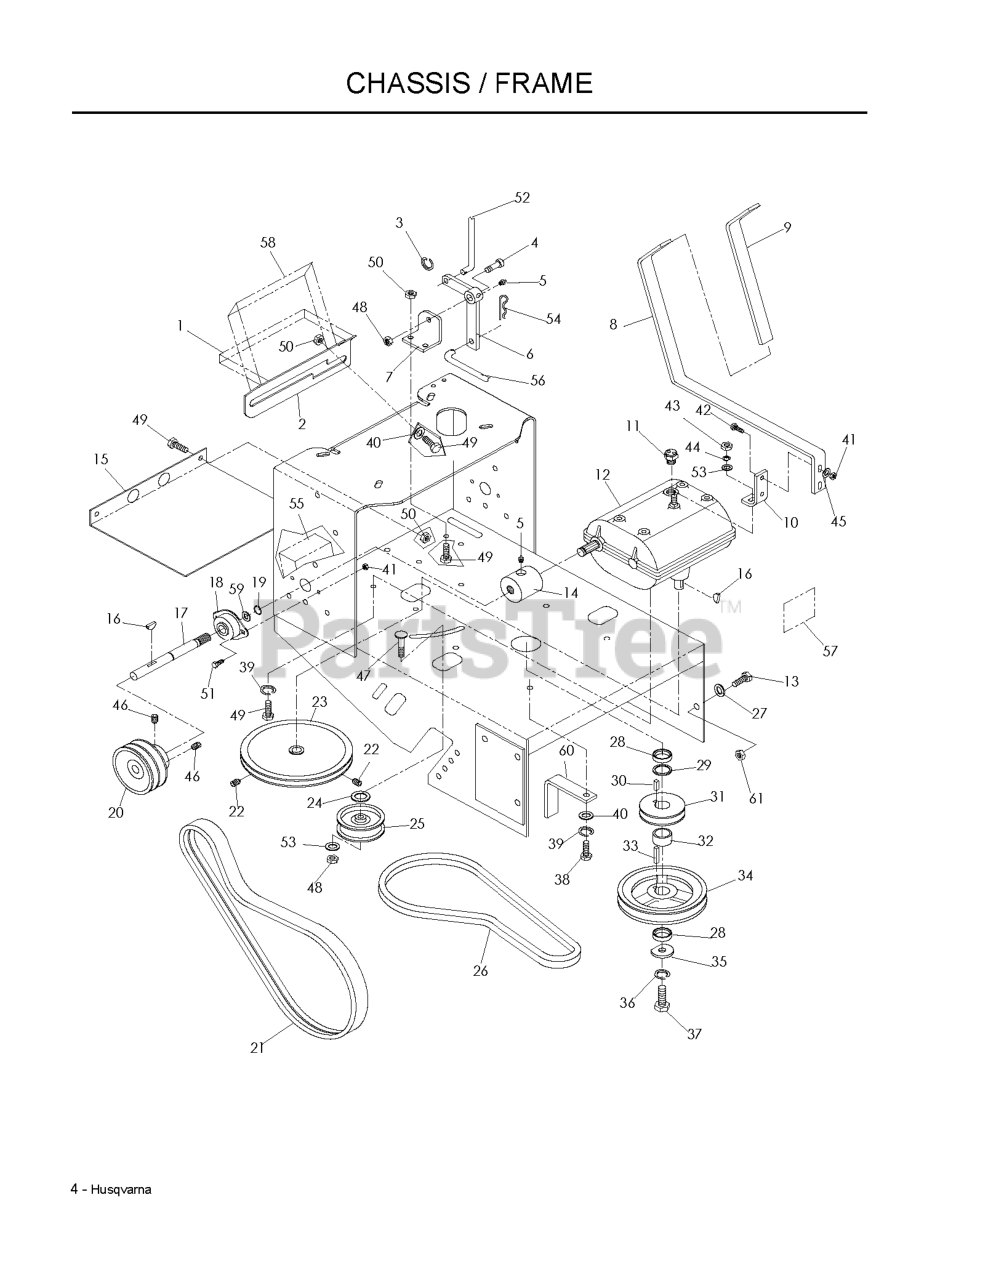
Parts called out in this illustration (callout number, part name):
1	DECAL, SHIFTER
2	SHIFTER PLATE
4	SB 12C X 34
5	ZERK
8	SHIFTER ARM
9	SHIFTER GRIP
10	SHIFTER BRACKET
11	SWITCH, TRANS
12	TRANSMISSION WB
13	HCS 7/16C X 1 1/2
15	LOWER BELT SHIELD
16	KEY, #9 WOODRUFF
17	DRIVE SHAFT
19	RETAINER RING
20	PULLEY, DRIVE (36 & 48)
20	DRIVE PULLEY (32)
21	DRIVE BELT (32)
21	BELT, DRIVE 36/48
22	SETSCREW, 1/4-20 NYLOC
23	PULLEY, INPUT
24	WASHER, 3/8 SPEC
25	IDLER PULLEY
26	BELT, TRANSMISSION
27	WASHER 7/16 FLAT ZD
29	BUSHING, 10GA MACHINERY
30	SQUARE KEY - 1/4 X .5
33	KEY 1/4 SQ X 1 1/8
34	PULLEY, ENGINE
35	SPINDLE WASHER
36	WASHER 7/16 LOCK
37	HCS 7/16F X 1 1/2
38	HCS M8-1.25 X 30MM
39	WASHER.LOCK.HVY.HLCL.SPR.5/16
40	WASHER 5/16 FLAT
41	NUT 1/4C CENTER LOCK
42	HCS 1/4C X 1
44	SLW 3/8 STD
45	WASHER 1/4 FLAT
46	SET SCREW 5/16 NYLOC
47	RHSNB 3/8C X 2
48	NUT 3/8C CENTERBLOCK
49	HCS 5/16C X 3/4
50	NUT 5/16C CENTERLOCK
51	HCS 1/4C X 5/8
53	WASHER 3/8 FLAT
54	HAIRPIN #4
55	DECAL, BELT DRIVE
56	BLADE ROD 36"
57	DECAL, EXHAUST
58	DECAL, CLUTCH
60	BELT GUIDE - LONG
61	NUT 7/16C CENTERLOCK
